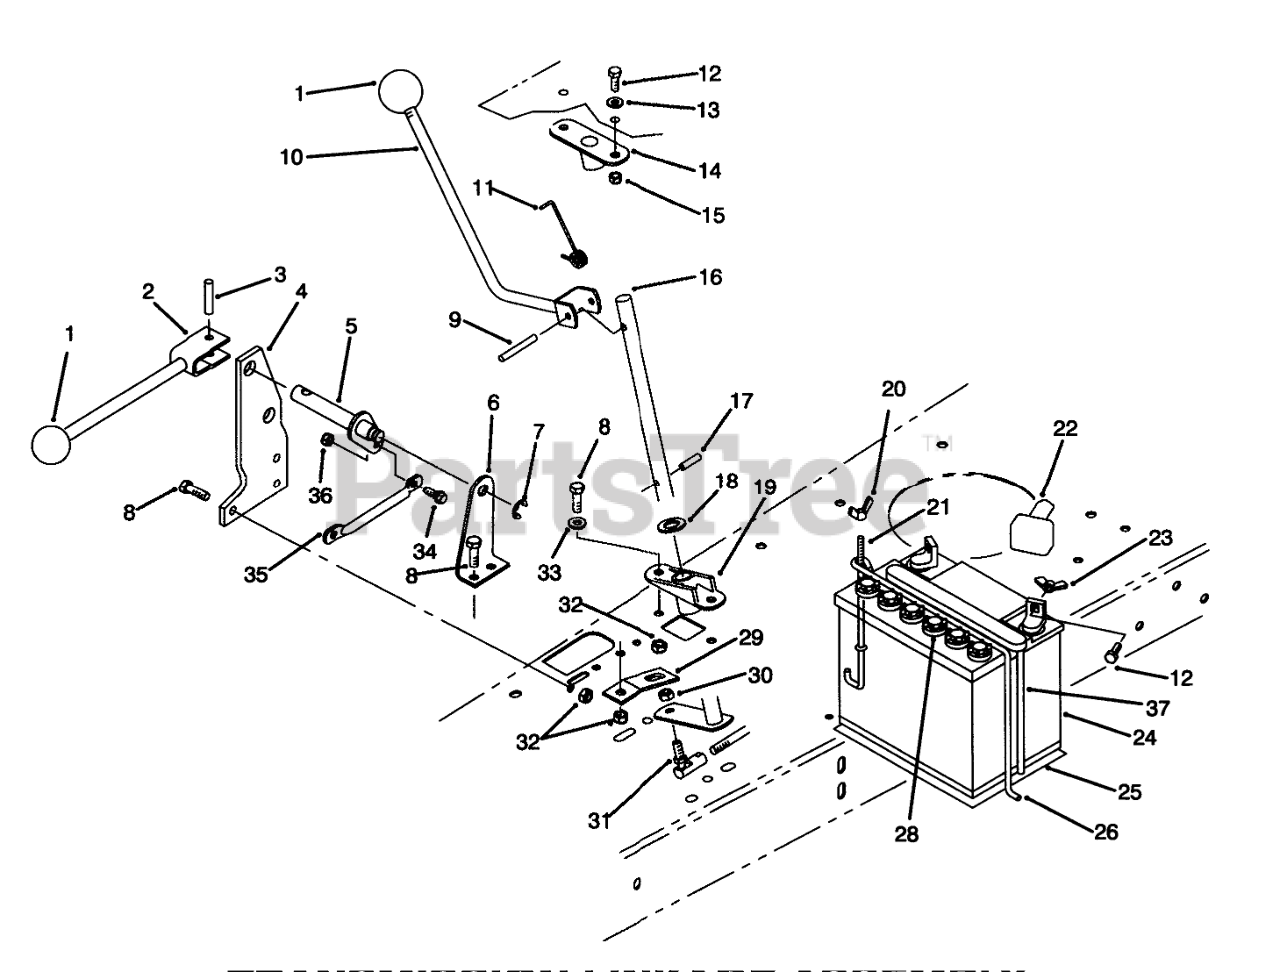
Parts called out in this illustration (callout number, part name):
2	Lever W.A.-Engage
3	PIN-ROLL
4	Pivot-Outer
5	PIVOT SHAFT WA
6	Bracket-Pivot, Inner
7	RING-RETAINING, EXTERNAL
8	SCREW-HH
9	PIN-ROLL
10	Lever W.A.-Shaft
11	SPRING-TORSION
12	SCREW-HH
13	WASHER-FLAT
14	SUPPORT-SHIFT SHAFT
15	NUT-LOCK, NI
16	SHAFT-SHIFT
17	PIN-SPRING
18	WASHER-THRUST
19	SUPPORT-LOWER SHIFTER
20	NUT-WING
21	POST-BATTERY
22	BOOT-TERMINAL
23	NUT-WING
24	Battery-12Volt (Incl. Ref. #28 & 37)
25	PAD-SKID, ANTI
26	HOLDDOWN-BATTERY
28	CAP-BATTERY
29	RETAINER-TRACTION SPRING
30	NUT-LOCK
31	JOINT-BALL
32	NUT-LOCK, NI
33	WASHER-PLAIN
34	SCREW-SHOULDER
35	LINK-BELLCRANK
36	NUT-HEX
37	TUBE-BATT DRAIN/80-2600
